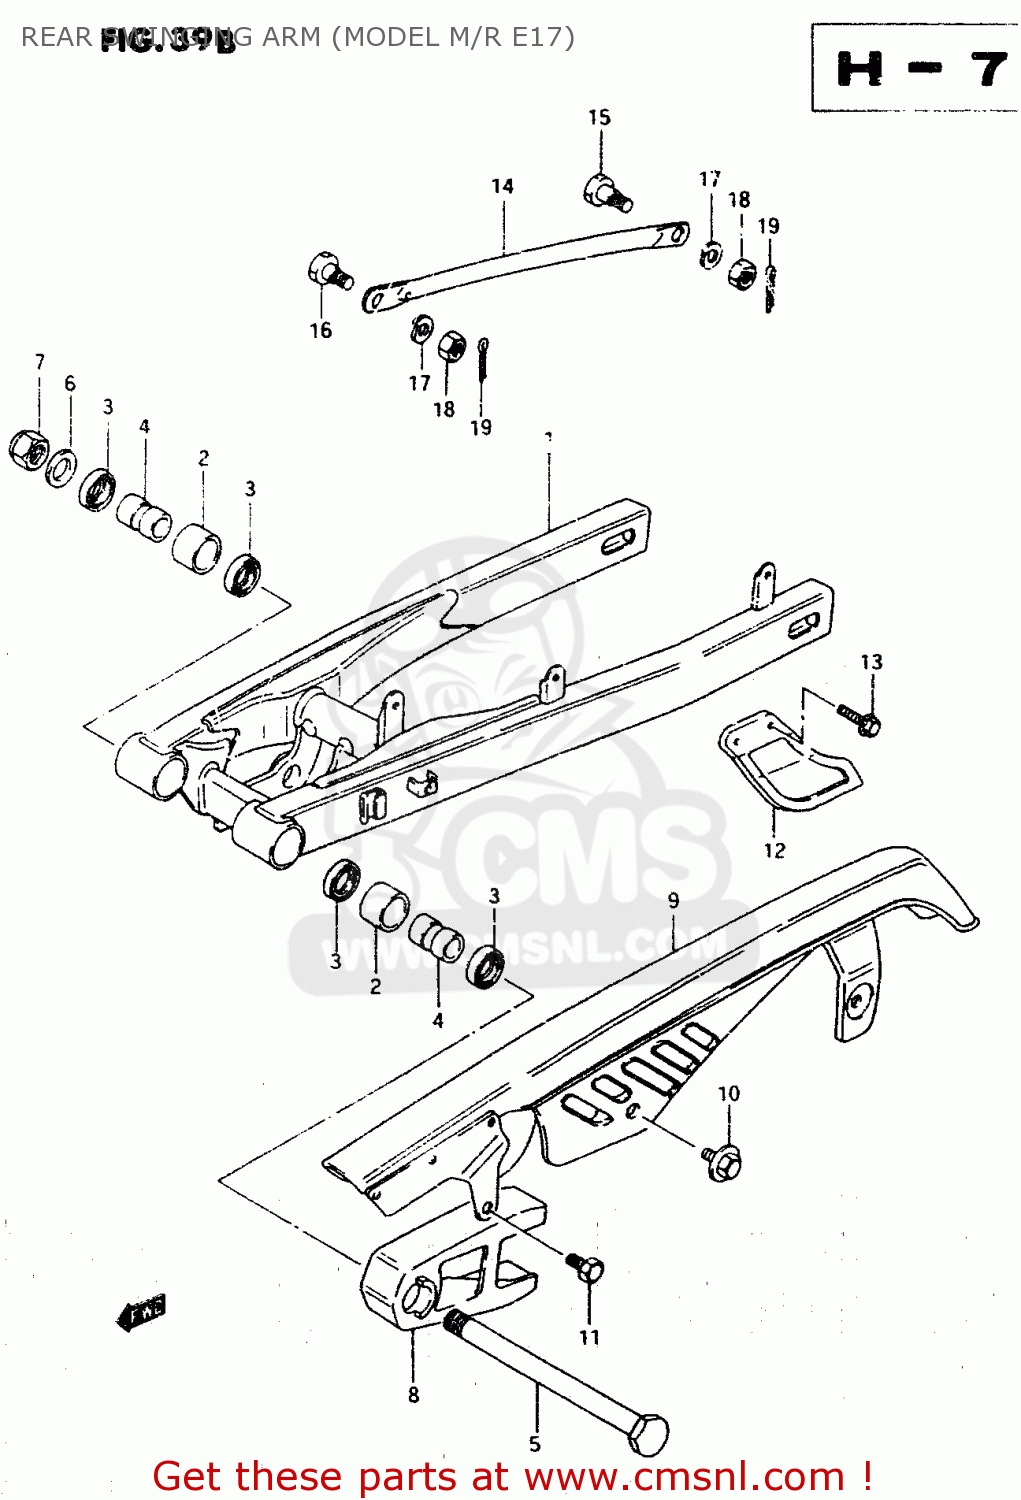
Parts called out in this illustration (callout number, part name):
1	SWINGING ARM ASSY, REAR (SILVER)
2	BUSHING,RR SWGARM PIVOT
3	OIL SEAL
4	SPACER,RR SWINGING ARM PIVOT
5	SHAFT,RR
6	WASHER
7	NUT 14MM
8	BUFFER,CHAIN TOUCH DEFENCE
9	CASE,CHAIN
10	BOLT(6X10)
11	BOLT
12	GUIDE,CHAIN
13	BOLT
14	TORQUE LINK,RR
15	BOLT(8X26.5)
16	BOLT(8X22)
17	LOCK WASHER
18	NUT
19	PIN 20X20
